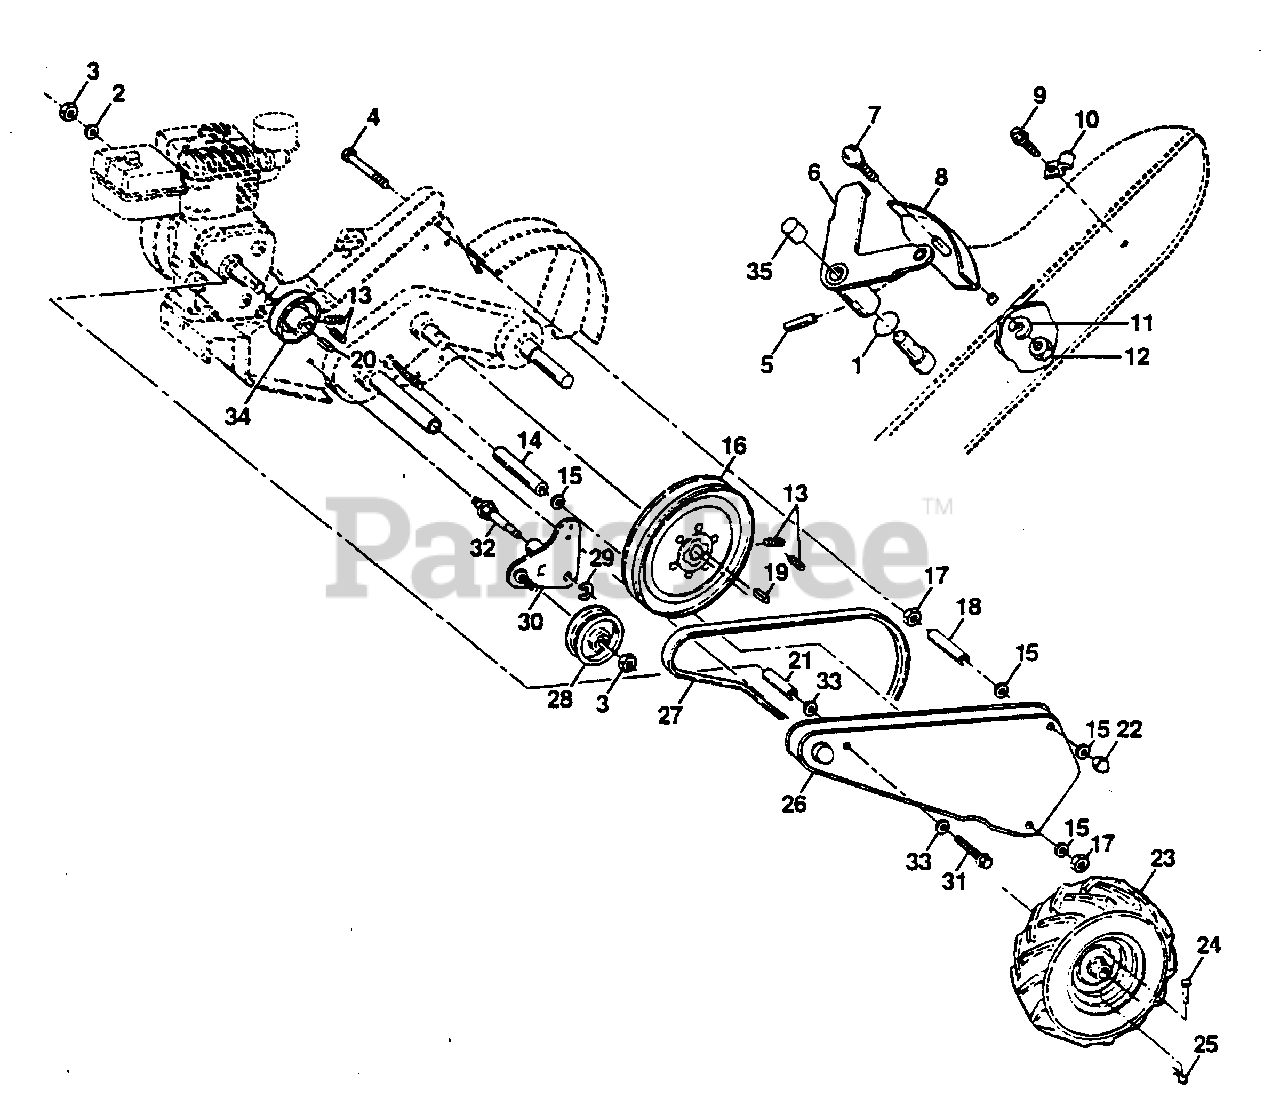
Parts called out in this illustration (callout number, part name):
1	O-Ring (AYP part number)
2	Washer, Lock 3/8 (AYP part number)
3	Nut, Hex 3/8-16 (AYP part number)
4	Bolt, Hex Head 5/16-18 x 4-1/2 (AYP part number)
5	Pin, Roll (AYP part number)
6	Lever, Shift
7	Bolt, Carriage 1/4-20 x 1/2 Grade 5 (AYP part number)
8	Plate, Shift Indicator (AYP part number)
9	Screw, Hex Washer Head, Slotted #10-24 x 1/2 (AYP part number)
10	Clip (AYP part number)
11	Washer, Lock 1/4 (AYP part number)
12	Nut, Hex 1/4-20 (AYP part number)
13	Screw, Set, Hex 5/16-18 x 3/8 (AYP part number)
14	Spacer, Split (AYP part number)
15	Washer 11/32 x 11/16 x 16 Gauge (AYP part number)
16	Sheave, Transmission (AYP part number)
17	Nut, Hex 5/16-18 (AYP part number)
18	Spacer (AYP part number)
19	Key, Square 3/16 x 1-1/8 (AYP part number)
20	Key, Square (AYP part number)
21	Spacer, Split .523 x .718 x 2 (AYP part number)
22	Nut, Cap 5/16-18 (AYP part number)
23	Tire (AYP part number)
24	Rivet, Drilled
25	Clip, Hairpin (AYP part number)
26	Guard, Belt (AYP part number)
27	V-Belt (AYP part number)
28	Pulley, Idler (AYP part number)
29	Ring, Klip (AYP part number)
30	Bracket, Idler (AYP part number)
31	Bolt, Hex Head 1/2-20 x 2-3/4 (AYP part number)
32	Shaft, Idler Arm (AYP part number)
33	Washer (AYP part number)
34	Sheave, Engine (AYP part number)
35	Cap, Plunger (AYP part number)
